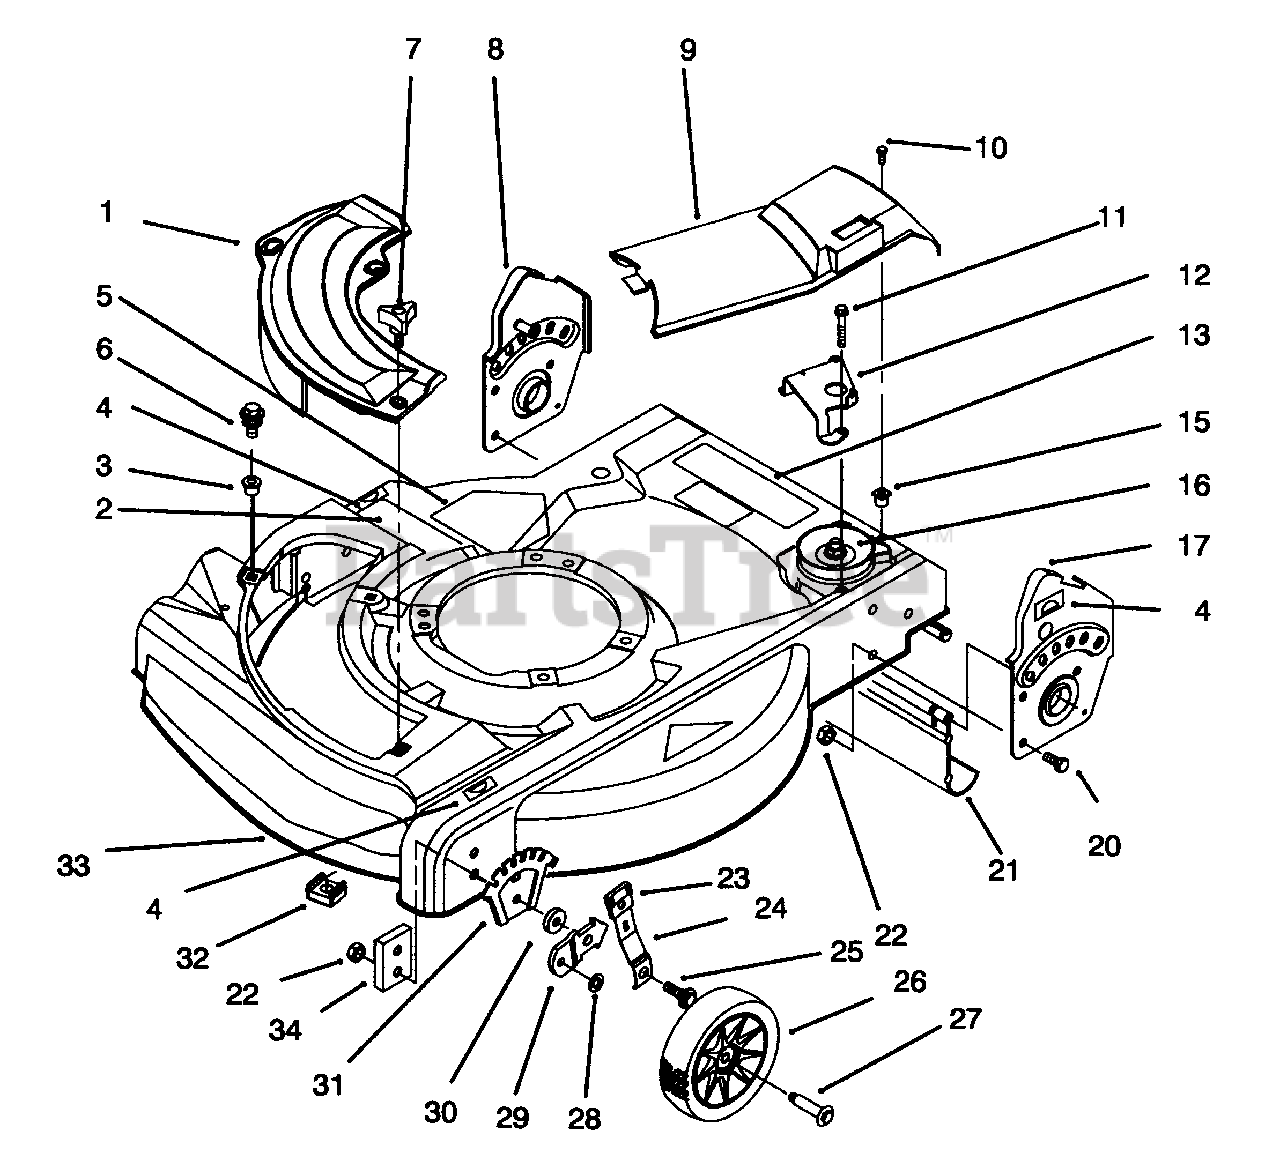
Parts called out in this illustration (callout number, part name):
1	Cover Plate, Mulch
2	Decal-Danger (English)
3	Grommet-Plastic
4	Decal-H.O.C. L.H.
5	Decal-Danger (English)
6	Screw-Thread Forming
7	Knob
8	Handle Bracket Ass'y-R.H.
9	Cover-Drive
10	Screw
11	Screw-Thread Forming
12	Guide-Transmission
13	Decal-Warning (English)
15	Grommet-Shroud Mtg.
16	Gear Case Ass'y
17	Handle Bracket Ass'y-L.H.
20	Screw-Hex. Hd.
21	Shield-Trailing
23	Knob-H.O.C.
24	Arm-Spring
25	Bolt-Shoulder
26	Wheel Assembly-6"
27	Bolt-Wheel
29	Bracket-H.O.C.
31	Plate H.O.C.
32	Nut-Cage
33	Housing & Baffle Ass'y (Incl. Ref. #2-6, 13 & 32)
34	Plate-Baffle
